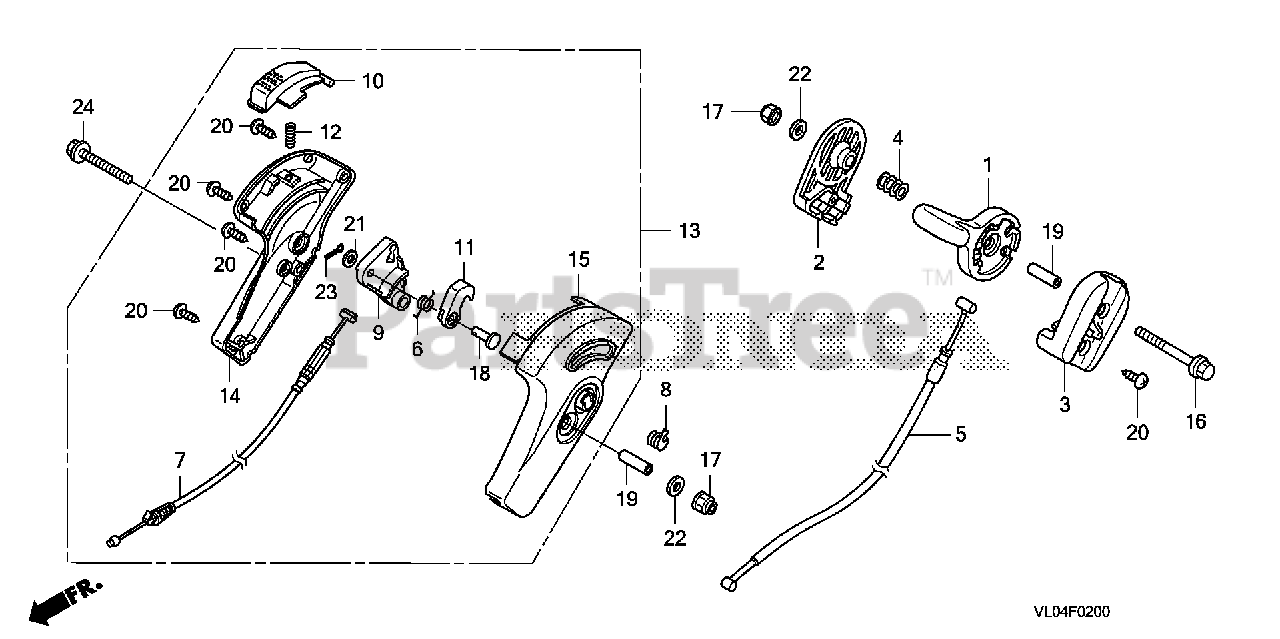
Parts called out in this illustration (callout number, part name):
1	LEVER, THROTTLE
2	CASE, R. THROTTLE LEVER
3	CASE, L. THROTTLE LEVER
4	SPRING, THROTTLE LEVER
5	CABLE, THROTTLE
6	SPRING, LOCK LEVER RETURN
7	CABLE, ROTO-STOP
8	SPRING, R. STOP RETURN
9	ARM, ROTO-STOP CABLE
10	KNOB, PUSH
11	LEVER, LOCK
12	SPRING, LEVER RETURN
13	CONTROL ASSY., ROTO-STOP
14	CASE, ROTO-STOP (R)
15	CASE, ROTO-STOP (L)
16	BOLT, FLANGE (6X65)
17	NUT, NYLON LOCK (6MM)
18	PIN, CLUTCH LEVER
19	COLLAR, THROTTLE
20	SCREW, TAPPING (4X12)
21	WASHER, PLAIN (6MM)
22	WASHER, PLAIN (6MM)
23	PIN, LOCK (6MM)
24	BOLT, FLANGE (6X65)
